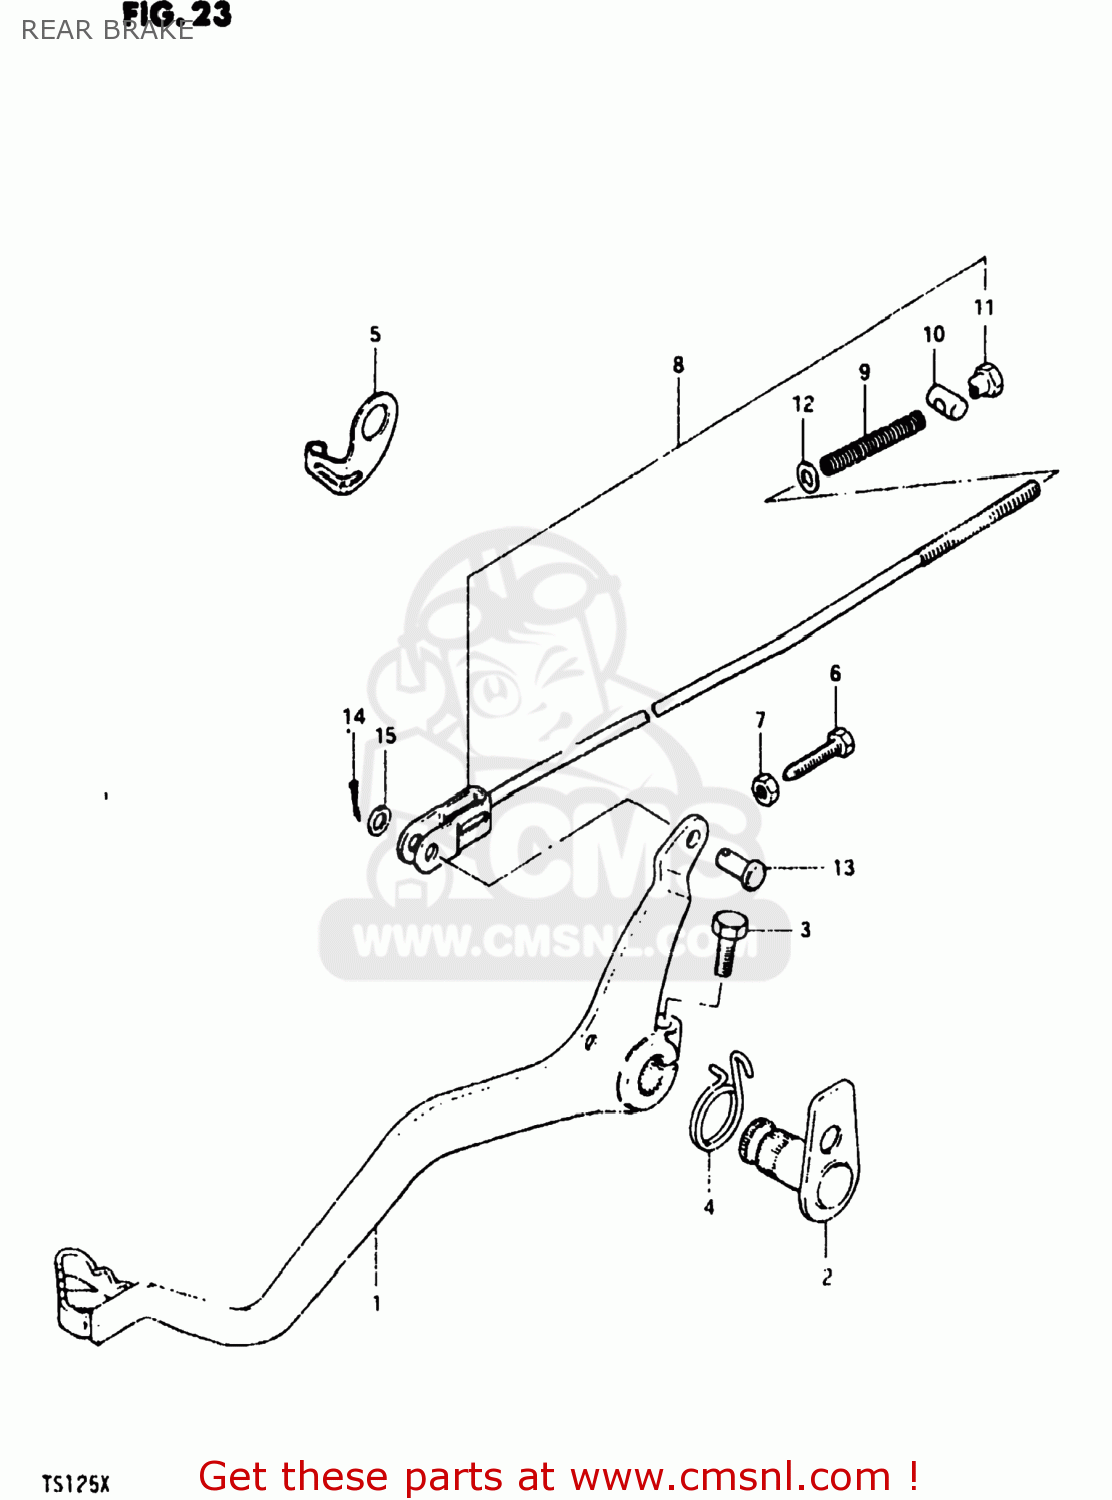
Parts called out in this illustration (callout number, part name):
1	PEDAL,BRAKE
2	ARM,BRAKE PEDAL
3	BOLT
4	SPRING
5	HOOK,STOP LAMP SWITCH SPRING
6	BOLT(6X23)
7	NUT
8	ROD ASSY,RR BRAKE
9	SPRING
10	PIN
11	NUT
12	WASHER
13	PIN(L:13.5)
14	PIN 20X20
15	WASHER
